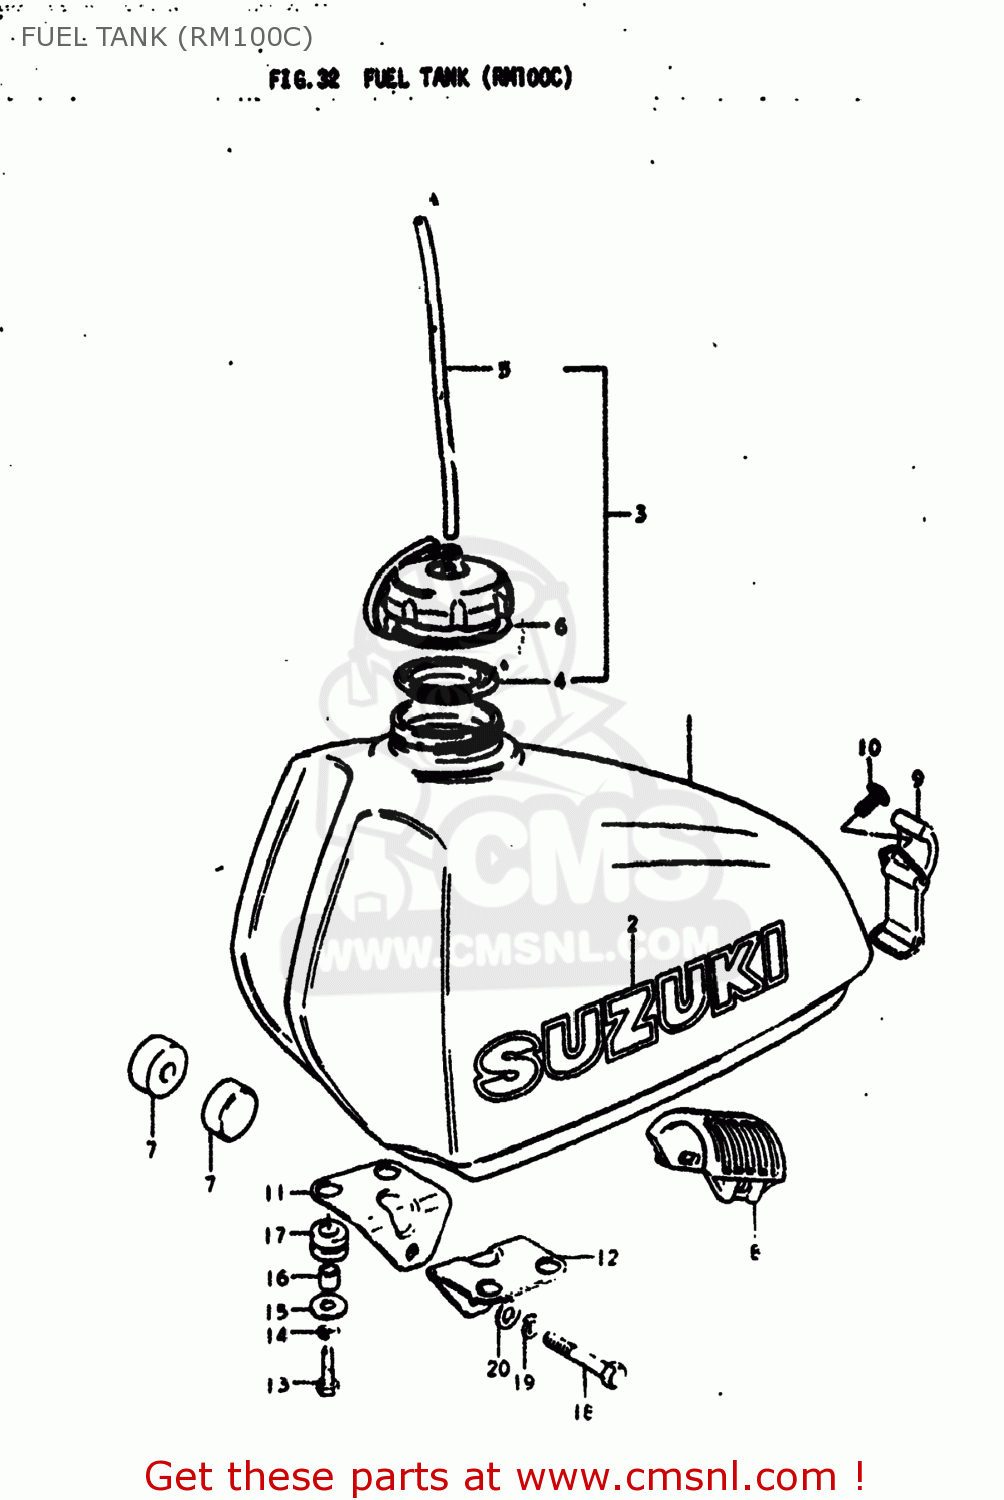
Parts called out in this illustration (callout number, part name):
1	TANK ASSEMBLY,FUEL
2	EMBLEM(BLACK)
3	CAP ASSY,FUEL TANK
4	GASKET,FUEL TANK CAP (NAS)
5	HOSE
6	BAND,FUEL TANK CAP
7	CUSHION
8	CUSHION,FUEL TANK
9	BAND
10	SCREW(6X18)
11	BRACKET,FUEL TANK
12	BRACKET,FUEL TANK
13	BOLT
14	LOCK WASHER
15	WASHER (6.5X20X1.2)
16	SPACER (6.8X10X10)
17	CUSHION
18	BOLT
19	LOCK WASHER
20	WASHER
